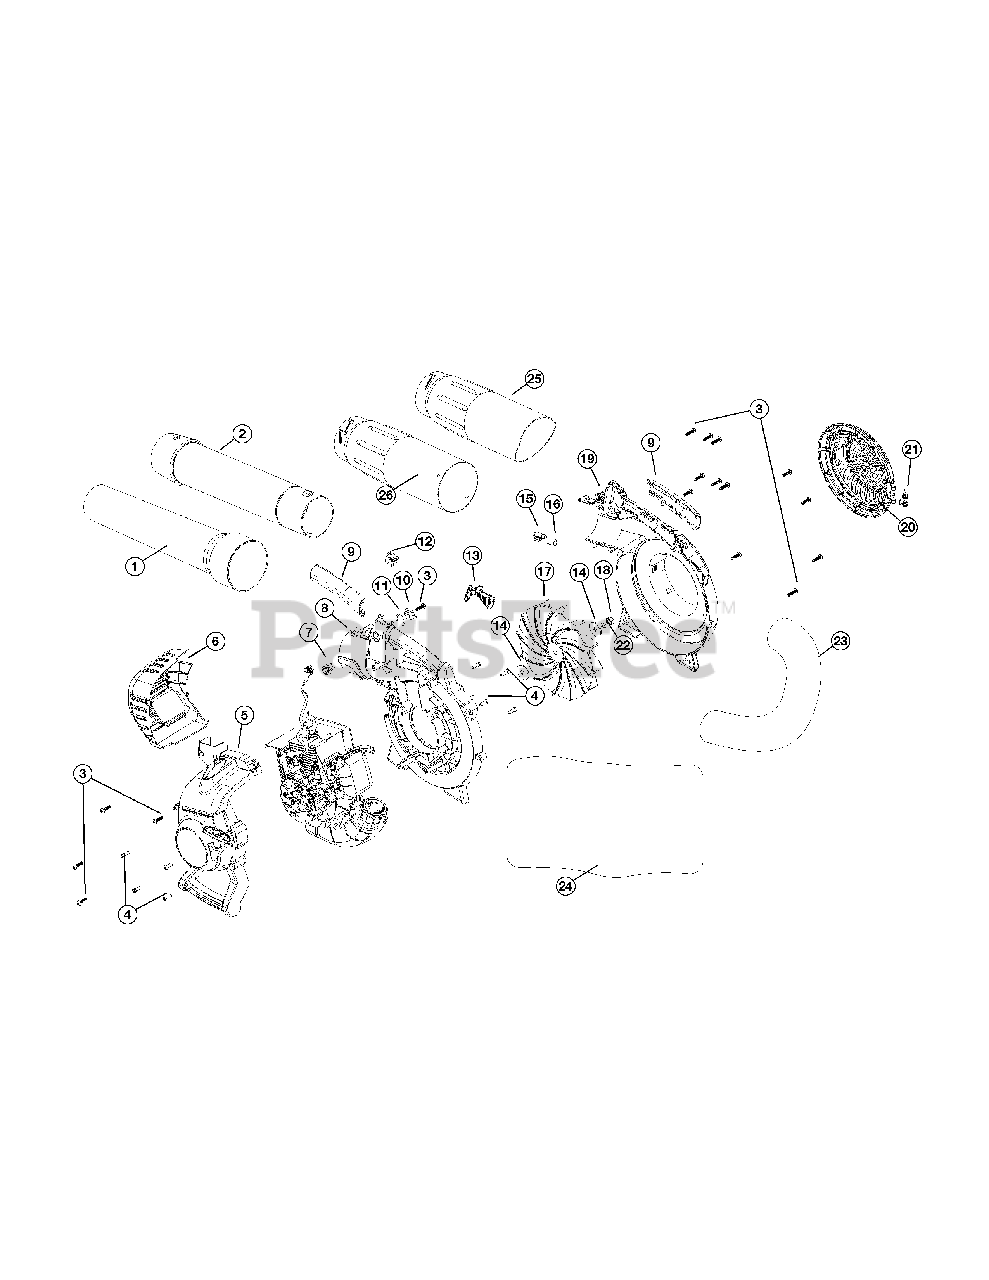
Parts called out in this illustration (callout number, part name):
1	Lower Tube
2	Upper Tube
4	Screw
5	Engine Cover Assembly (Incl. 3 & 4)
6	Muffler Cover Assembly (Incl. 3)
7	Outer Trigger Lock
8	Impeller Housing (Incl. 9)
9	Handle Grips
10	Inner Trigger Lock
11	Wavey Washer
13	Throttle Trigger
14	Washer
15	Latch Tube
16	Latch Spring
17	Impeller
19	Impeller Housing (Incl. 9)
20	Intake Cover
21	Spring
22	Lock Washer
25	Upper Vac Tube
26	Lower Vac Tube
